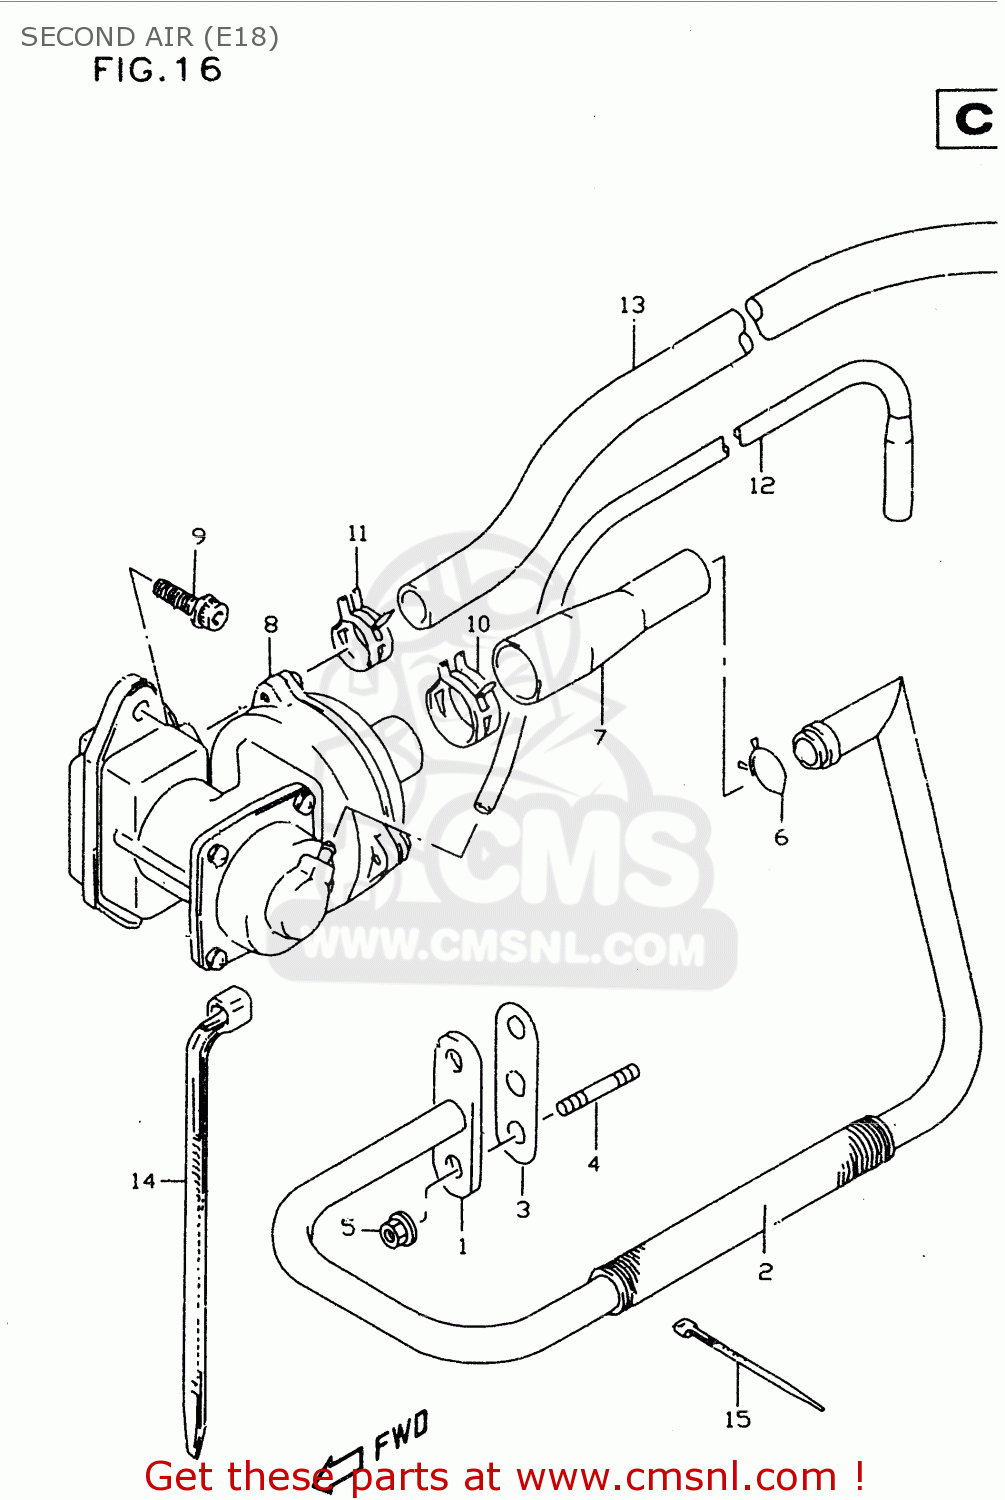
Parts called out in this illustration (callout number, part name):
1	PIPE,2ND AIR
2	PROTECTOR, 2WD AIR PIPE
3	GASKET,SECOND AIR PIPE (N (NAS)
4	STUD BOLT
5	NUT
6	CLIP
7	HOSE, 2ND AIR
8	VALVE ASSY,2ND AIR REED
9	BOLT
10	CLIP
11	CLIP
12	HOSE(4X7X600)
13	HOSE(12X16X600)
14	CLAMP L:165
15	CLAMP(L:145)
